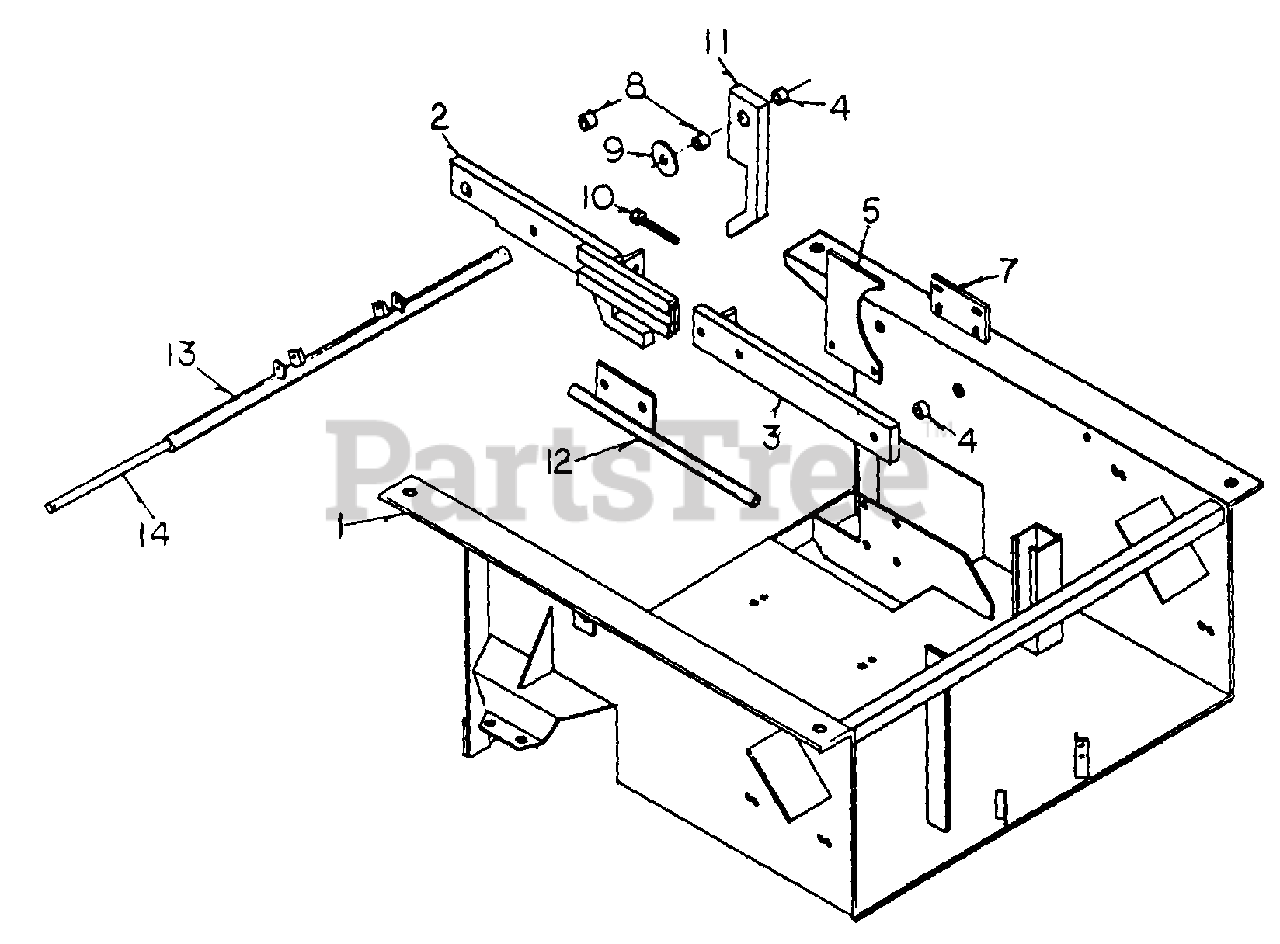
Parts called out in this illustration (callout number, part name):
1	BASE
2	DECK LIFT ARM - Front RH
3	DECK LIFT ARM - Back
4	BUSHING, Short
5	BELT RETAINER
7	BELT RETAINER MOUNT
8	BUSHING - Long
10	DECK BELT ADJUSTMENT BOLT
11	FORWARD NOSE DOWN LOCK
14	CROSS BAR PIN
